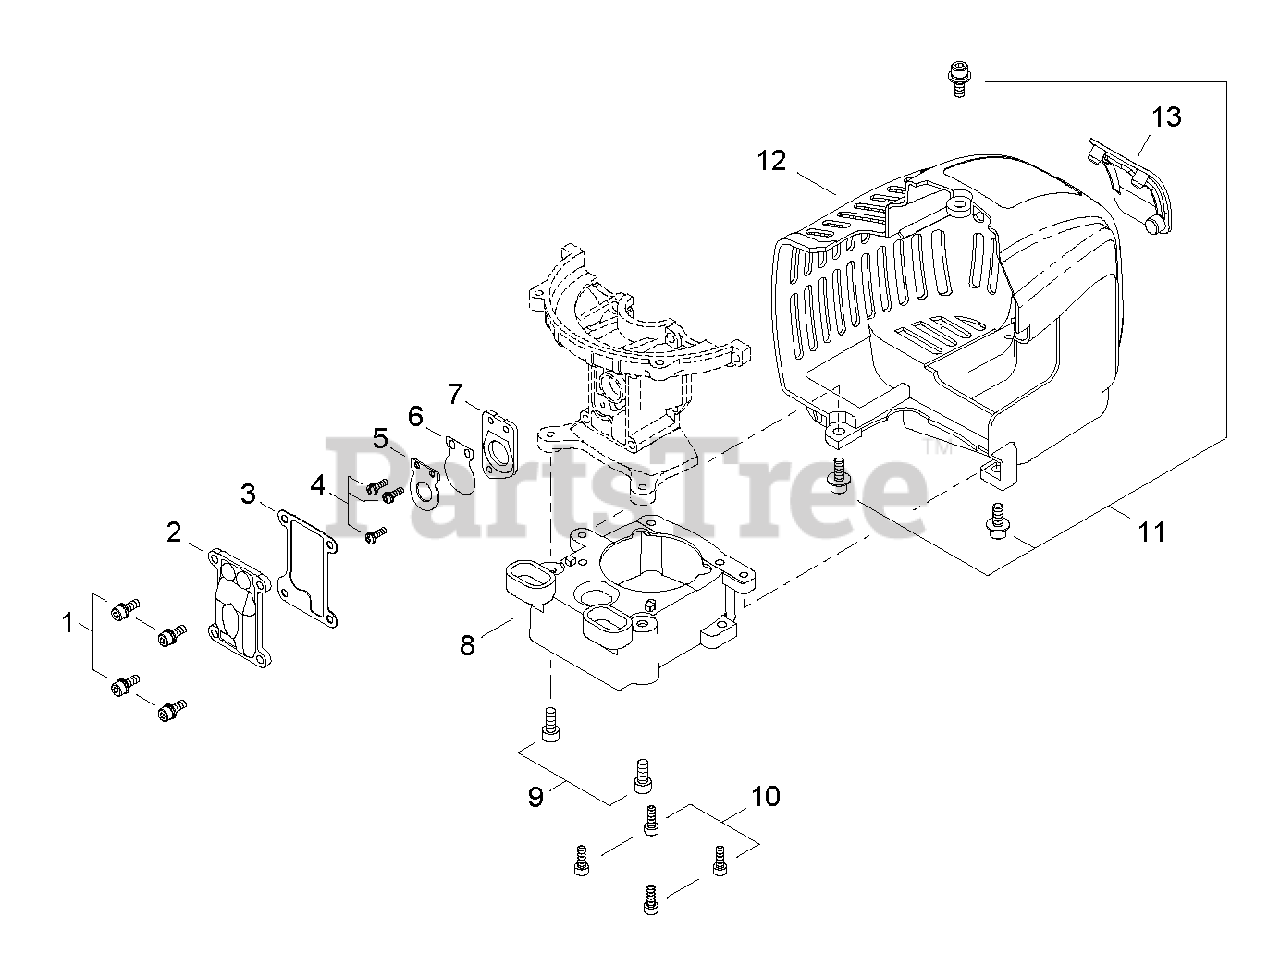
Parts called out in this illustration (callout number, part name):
1	SCREW - 4X12
2	COVER, REED VALVE
3	GASKET, REED VALVE
4	SCREW - 3X10
5	STOP, REED VALVE
6	VALVE, REED
7	PLATE, REED BACKING
8	ADAPTOR, GEAR CASE
9	SCREW - 5X12
10	SCREW - 4X12
11	SCREW - 5X14
12	COVER, ENGINE
13	COVER, SPARK PLUG
